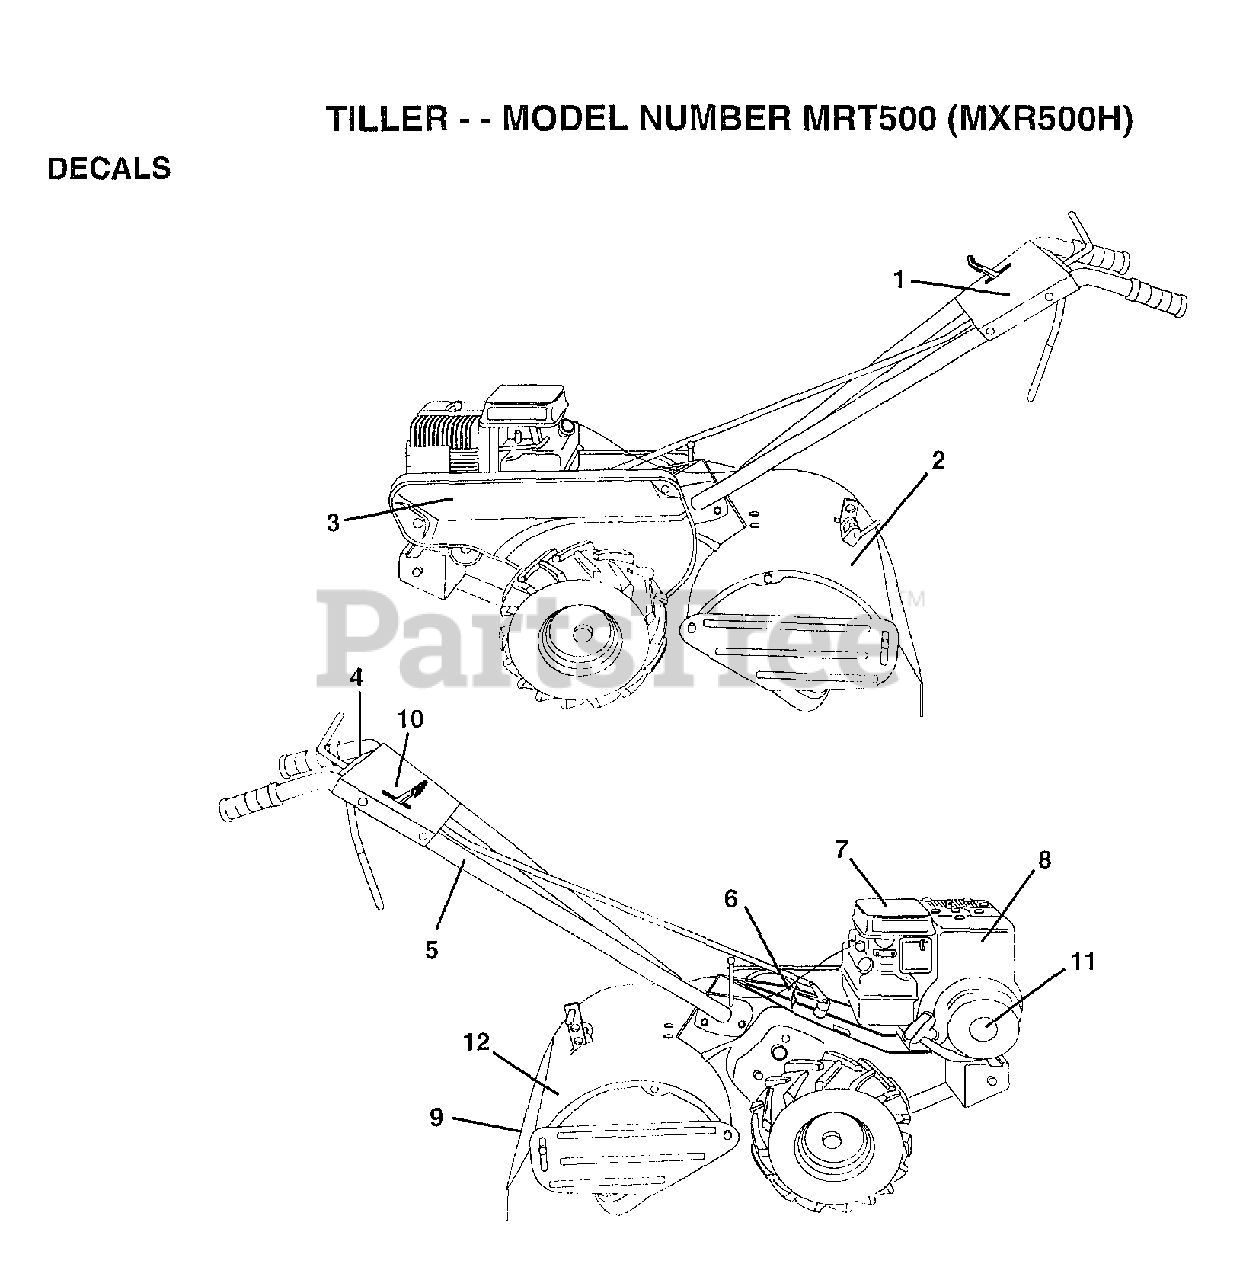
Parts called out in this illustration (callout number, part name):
1	DECAL CNTRL PANEL
2	DECAL SHIELD TINE
3	DECAL GUARD BELT
5	DECAL TI
6	DECAL CRT
7	DECAL TI
8	DECAL, BRIGGS & STRATTON
10	"DECAL CONTROL,PNL"
12	DECAL.CAUTION
